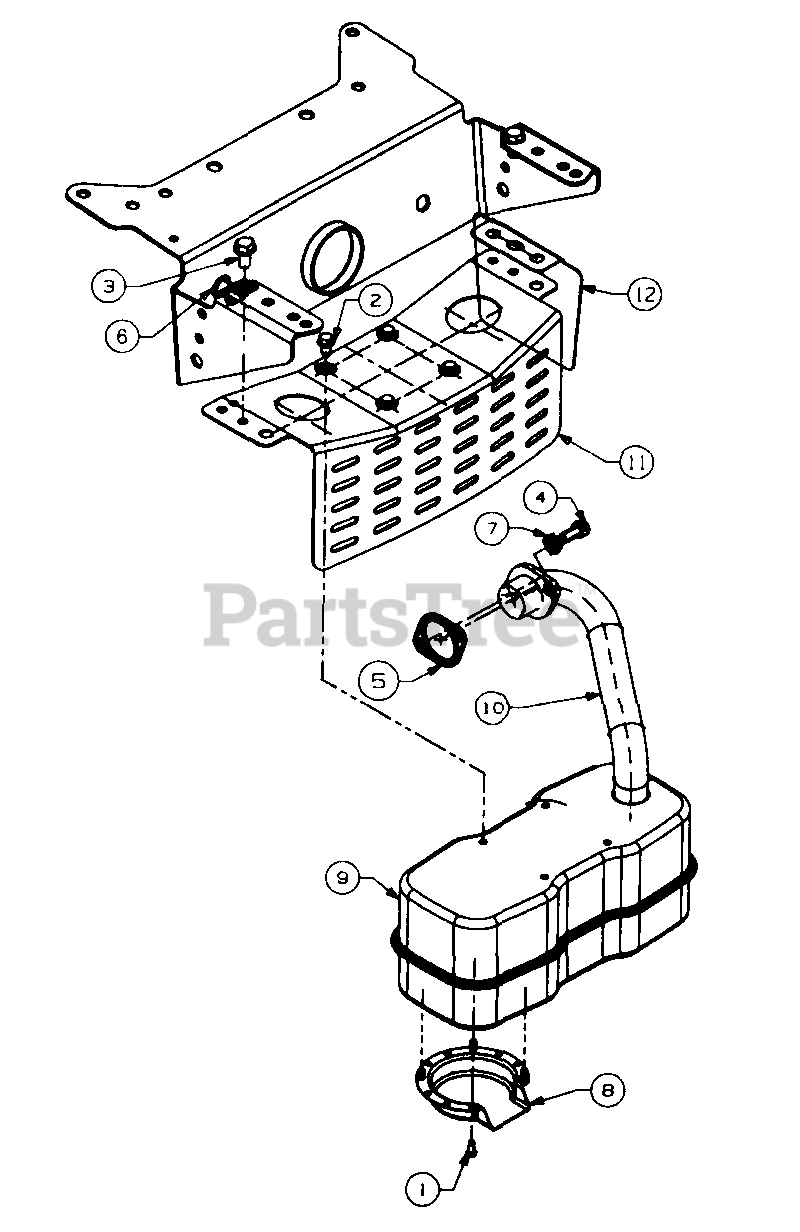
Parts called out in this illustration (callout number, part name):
1	Hex Slot Scr #8-32 x .38" Lg
2	Hex Wash. TT-Tap Scr. 1/4-20 x .5" Lg.
3	Hex Wash Hd. TT-Tap Scr. 5/16-18 x .62" Lg.
4	Socket Hd. Bolt 5/16-18 x .62" Lg.
5	Exhaust Gasket
6	Clamp
7	L-Wash. 5/16" I.D.
8	Muffler Deflector
9	Muffler
10	Exhaust Pipe
11	Muffler Bracket
12	Shield Bracket
